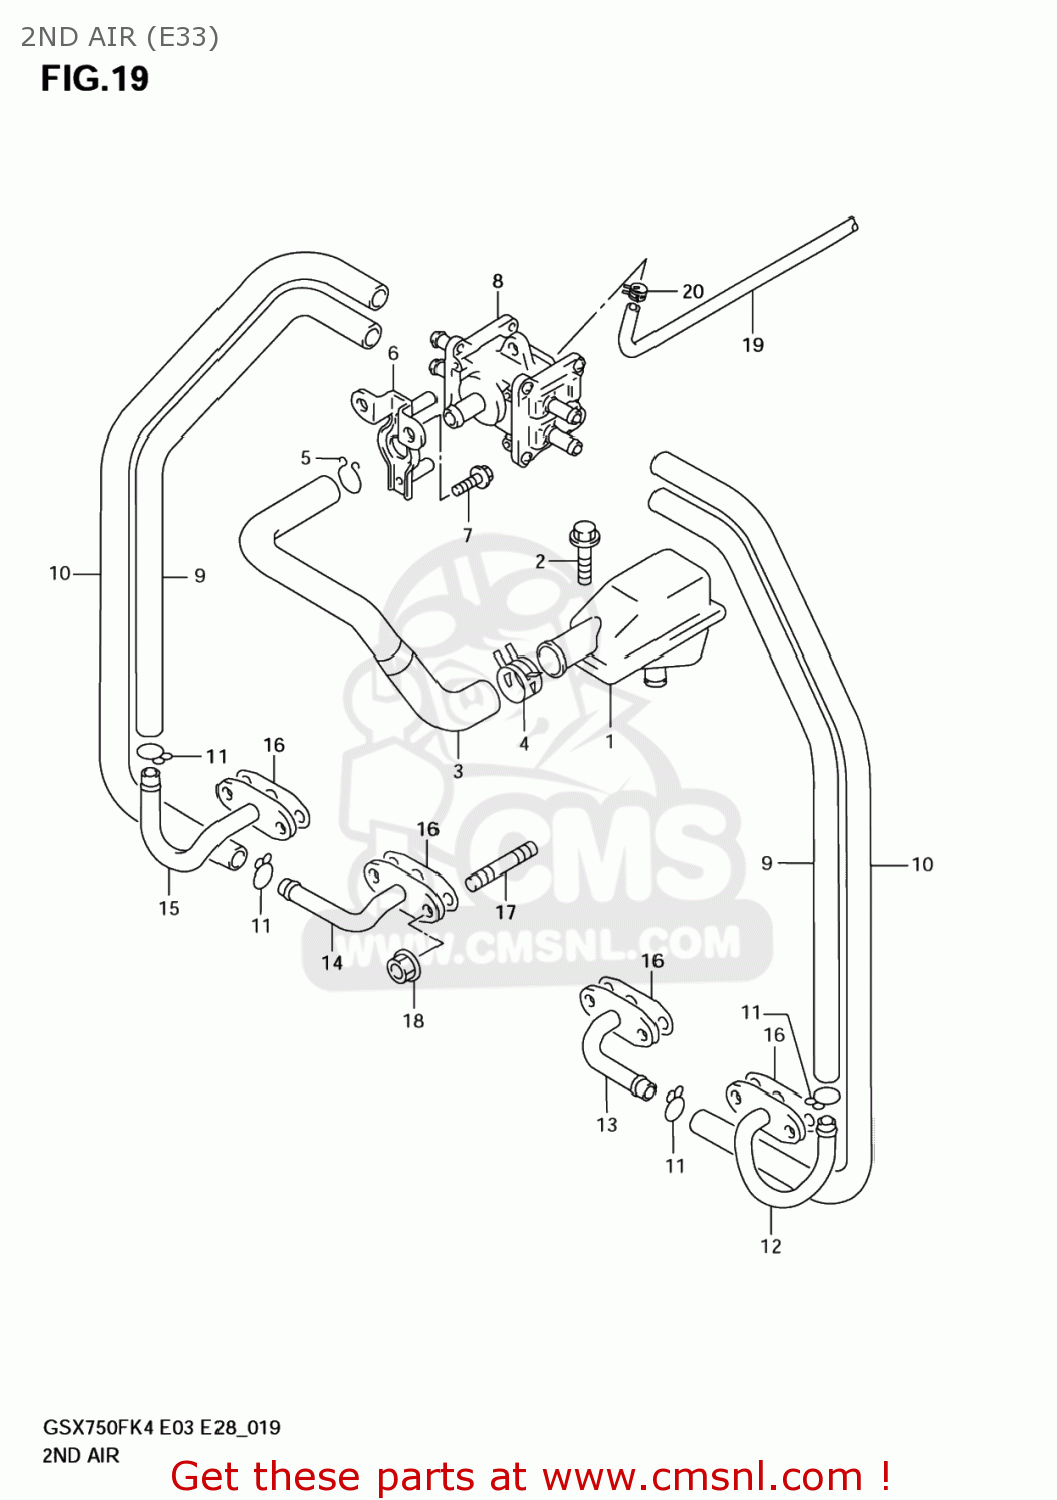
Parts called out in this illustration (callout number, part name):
1	CLEANER ASSY,2ND AIR
2	BOLT
3	HOSE,2ND AIR CLEANER
4	CLIP
5	CLIP
6	BRACKET,2ND AIR VALVE
7	BOLT
8	VALVE ASSY,2ND AIR
9	HOSE,2ND AIR VALVE OUTER
10	HOSE,2ND AIR VALVE INNER
11	CLIP
12	PIPE,2ND AIR NO.1
13	PIPE,2ND AIR NO.2
14	PIPE,2ND AIR NO.3
15	PIPE,2ND AIR NO.4
16	GASKET,2ND AIR PIPE (NAS)
17	STUD BOLT
18	NUT
19	HOSE(4.5X8.5X600)
20	CLIP
